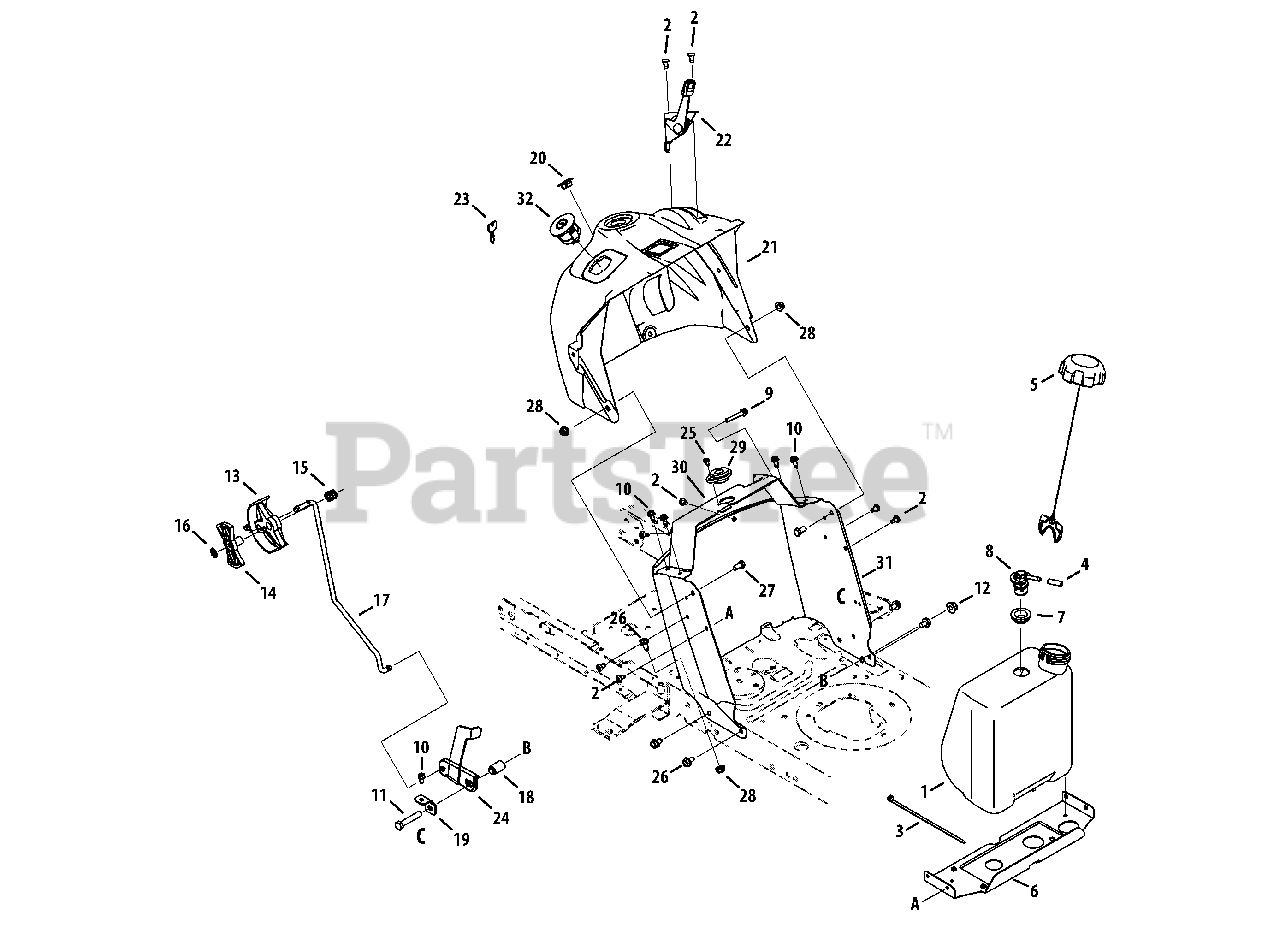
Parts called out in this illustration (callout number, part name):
1	Fuel Tank, 1.36 Gal.
2	Screw, Tap, 1/4-20, 0.500
3	Cable Tie, 36.0 Long
4	Hose Vent
5	Fuel Cap, 2.25"
6	Gas Tank Support Bracket
7	Rubber Grommet, 23 x 3.55
8	Rollover Valve
9	Hex Screw, 1/4-20 x 1.50
10	Tap Screw, 1/4-20, 0.625
11	Hex Screw, 3/8-16, 2.00, Gr5, Std
12	Flange Lock Nut, 3/8-16
13	Shift Lever
14	Index Control
15	Compr. Spring, .685 OD x .63
16	Lock Washer, 1/4
17	Speed Selector Control Rod
18	Flange Spacer, .390 X .671 X 1.095
19	Speed Latch
20	Choke Plug
21	Dash, Upper
22	Throttle/Choke Cable Assembly
23	Key, Assembly
24	Speed Latch - No RMC
25	Screw, #10-16 x .500
26	Tap Screw,5/16-18, 0.625
27	Hex Screw, 5/16-18 x .625
28	Flange Lock Nut, 5/16-18
29	Bearing, .628 ID x 1.36
30	Bracket, Steering Support
31	Dash, Lower No window
32	3 Position Key Switch
